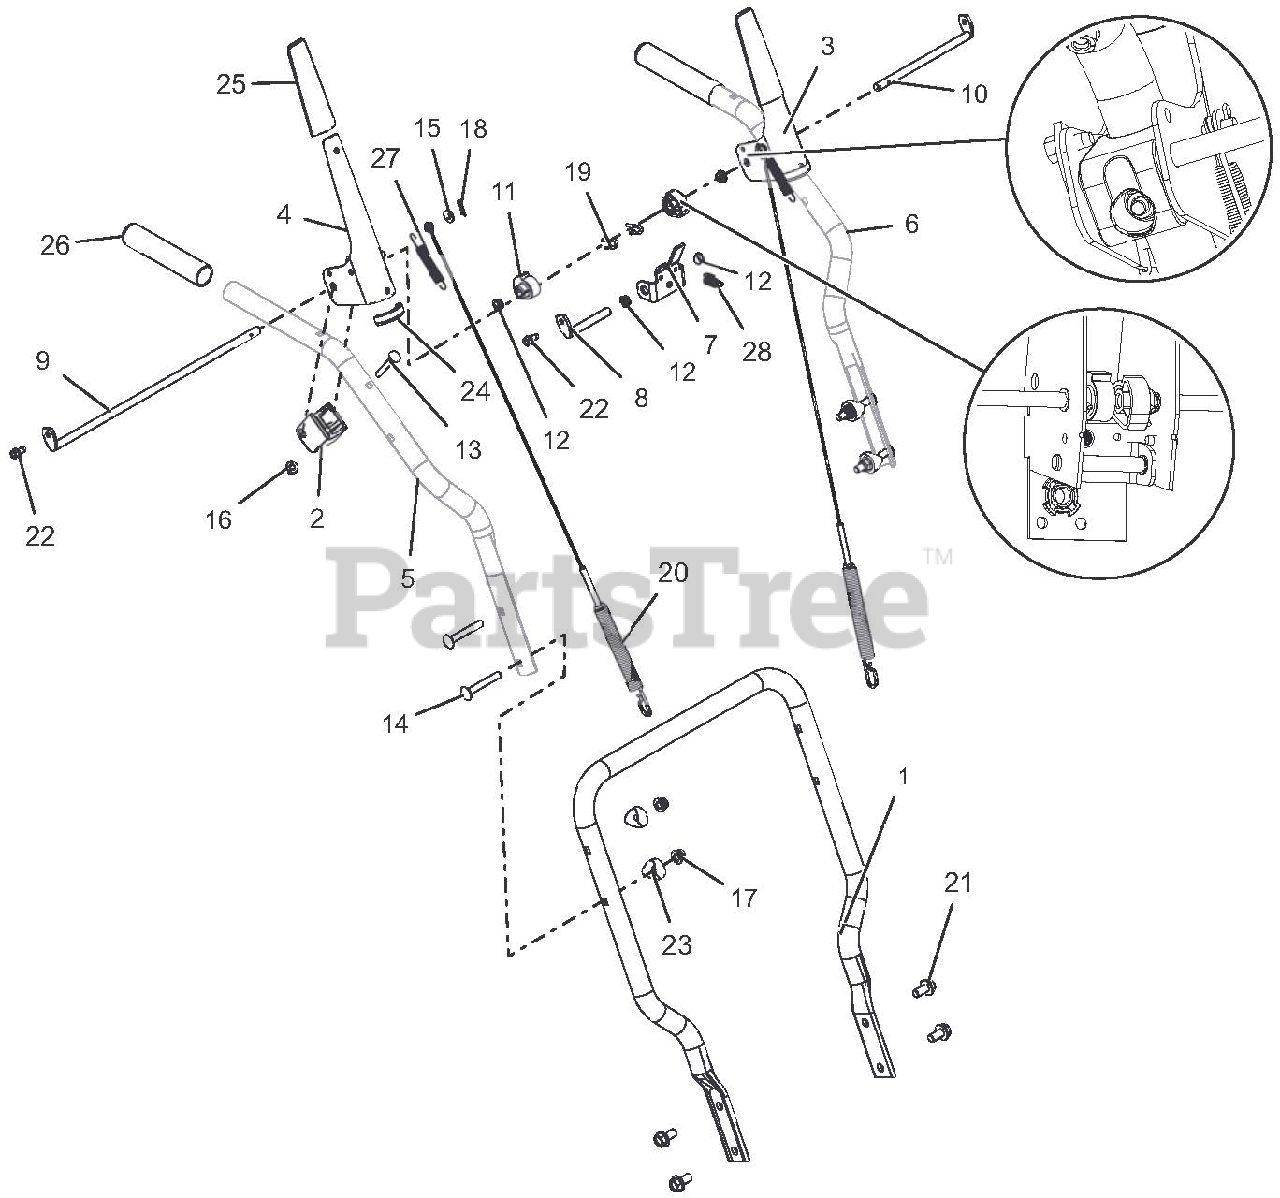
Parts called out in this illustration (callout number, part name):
1	HANDLEBAR, LOWER (COMPACT)
2	BLOCK, CLUTCH PADDLE
3	LEVER, CLUTCH-LH
4	LEVER, CLUTCH-RH
5	HANDLEBAR, UPPER - RH
6	HANDLEBAR, UPPER - LH
7	BRACKET, INTERLOCK ARM
8	ROD, PIVOT - INTERLOCK
9	ROD, PADDLE MOUNT - LONG
10	ROD, PADDLE MOUNT - SHORT
11	CAM, INTERLOCK
12	BUSHING, POLYLINER-.38 SNAPIN
13	BLT-RDHDXLSQNK .25-20X2.0 G5YZ
14	@BLT-RDHDSQNK .31-18X2.25 G5YZ
15	@WSHR-FL-STL.281X.62X.065 YWZC
16	@NUT-LK-TOP-FLG .25-20 YWZC
17	@NUT-LK-NYL-FLG .31-18 YWZC
18	PIN-HAIR INT .06X.18X.77
19	PIN, SPRING CLIP
20	CABLE, AUGER & UPPER TRACTION
21	BLT-SERHFWH .38-16X.75 YWZC
22	SCR-TAP .25-20X.50 HWH TR YWZ
23	SPACER, HANDLEBAR
24	EDGING, CLUTCH PADDLE - 2.00"
25	CLUTCH PADDLE SLEEVE - GRAY
26	HANDLE GRIP
27	SPRING, EXTENSION
28	SPRING-EXT .047X.438X1.45
